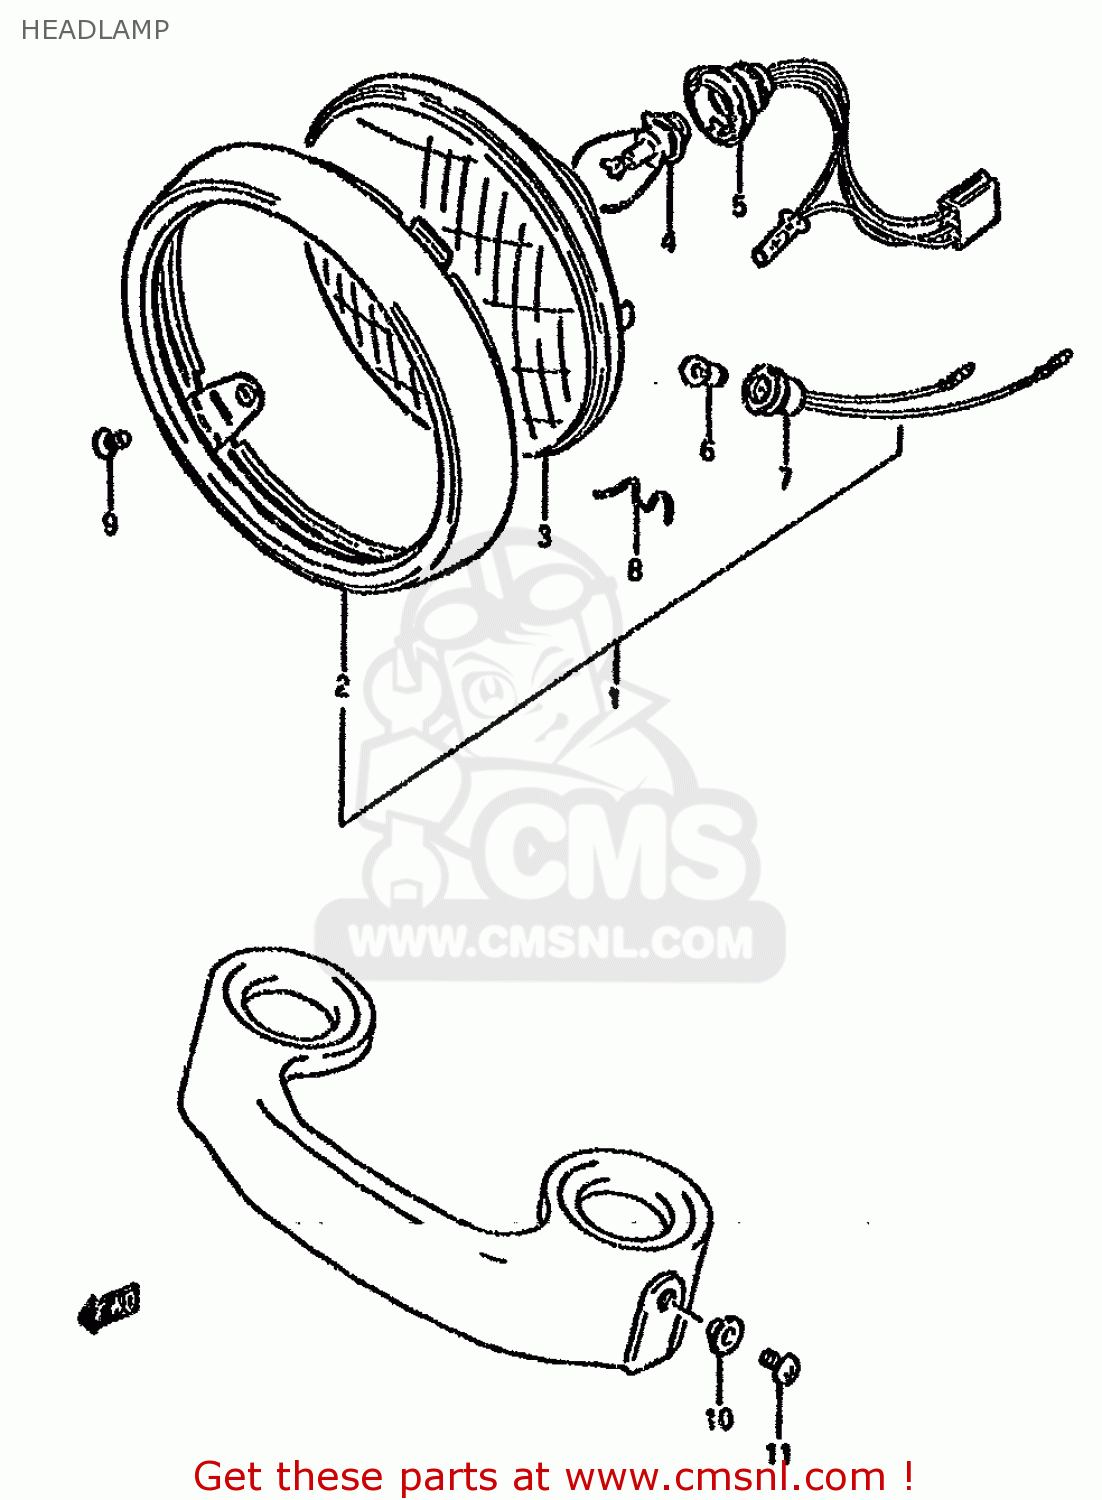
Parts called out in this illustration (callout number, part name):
1	HEADLAMP ASSY
2	RIM
3	LAMP UNIT
4	BULB
5	SOCKET
6	BULB(12V3.4W,STANLEY,A72A)
7	SOCKET
8	SPRING
9	SCREW
10	WASHER
11	SCREW
